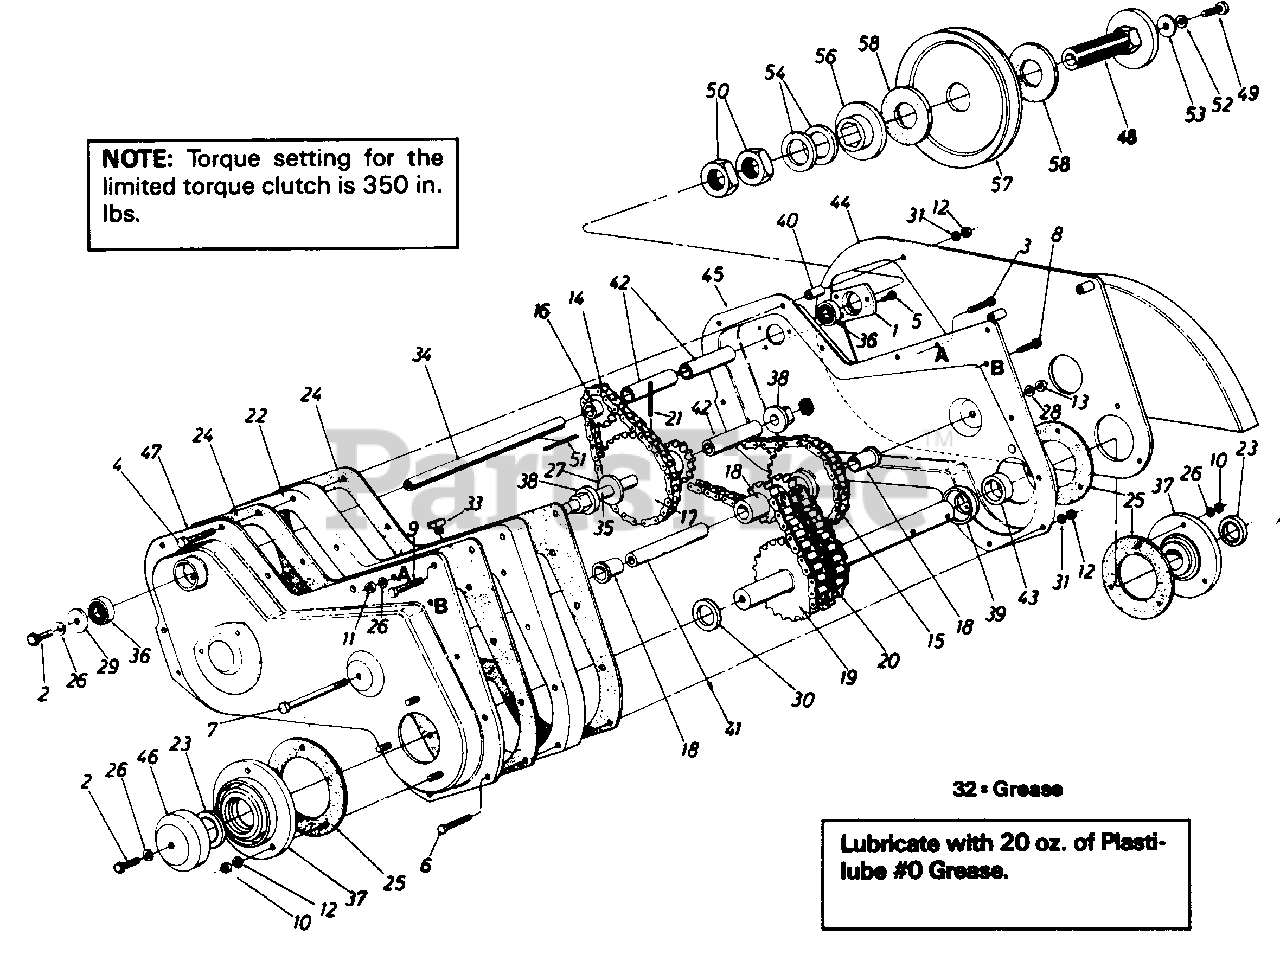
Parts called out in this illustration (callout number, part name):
1	Bearing Housing 1-3/8" Dia.
2	Hex Bolt 5/16-18 x .88" Lg. Spec.
3	Hex Bolt 5/16-18 x 1.50" Lg.
4	Hex Bolt 1/4-20 x 2.75" Lg.
5	Hex Wash. S- Tap. Scr. 1/4-20 x .50" Lg.
6	Hex Bolt 1/4-20 x 1.50" Lg.
7	Hex Bolt 3/8-16 x 4.5" Lg.
8	Hex Wash. Hd. Bolt 1/4-20 x 1.5" Lg.
9	Hex Wash. TT -Tap Scr. 5/16-18 x 1.75" Lg.
10	Hex Cent. L.-Nut 5/16-18 Thd.
11	Hex Nut 5/16-18 Thd.
12	Hex Nut 1/4-20 Thd.
13	Hex Nut 3/8-16 Thd.
14	#41 Chain 1/2" Pitch x 34 Links - Endless
15	#42 Chain 1/2" Pitch x 48 Links- Endless
16	Sprocket 10 Tooth .500" Pitch
17	10 & 28 Teeth Sprocket Ass'y.
18	8-2 & 28 Sprocket Sleeve Ass'y.
19	18-2 Sprocket Shaft Ass'y.
20	#50-2 Chain 5/8" Pitch x 28 Links- Endless
21	Spring Pin Spir. 1/4" Dia. x 1.50" Lg.
22	Spacer Block - Tiller Housing
23	Oil Seal Double Lip-1-1/4" Dia.
24	Gasket for Tiller Housing
25	Gasket for Brg.-Housing
26	L.-Wash. 5/16" I.D.
27	Fl.-Wash. .640" I.D. x 1.24" O.D.
28	L.-Wash. 3/8" I.D. Heavy Duty
29	Fl.-Wash. .344" I.D. x 1.125" O.D.
30	Special Washer
31	L.-Wash. 1/4" I.D.
33	Vent Plug
34	Jack Shaft .525" I.D. x 7.78" Lg.
35	Sprocket Shaft .63" Dia. x 5.0" Lg.
36	Ball Brg. .62" I.D. x 1.38" O.D.
37	Bearing Housing - 1-1/4"
38	Hex Flange Brg.
39	Spacer 1.25" I.D. x 2.0" O.D.
40	Spacer.28" I.D. x .62" O.D. x .90" Lg.
41	Spacer.38" I.D. x .62" O.D. x 3.44" Lg.
42	Spacer.62" I.D. x .88" O.D. x 1.56" Lg.
43	Spacer 1.25" I.D. x 1.62" O.D. x .50 Lg.
46	Dust Cap .320" Dia. Hole
49	Hex Bolt 5/16-18 x 1.25" Lg. Grade 5
50	Hex Jam Nut 1.0-14 x 28 Thd.
51	Sq. Key 3/16 x 1.50" Lg.
52	L.-Wash. 5/16" I.D.
53	Fl.-Wash. .344" I.D. x 1.125" O.D.
54	Spring Bell Wash. 1.0" I.D. x 2.0" O.D.
56	Floating Disc 3-1/4" O.D. x 1.0" I.D.
57	5/8 V-Pulley 1.50" I.D. x 6.50"
58	Friction Pad 3-1/4" O.D. x 1-3/8" I.D.
